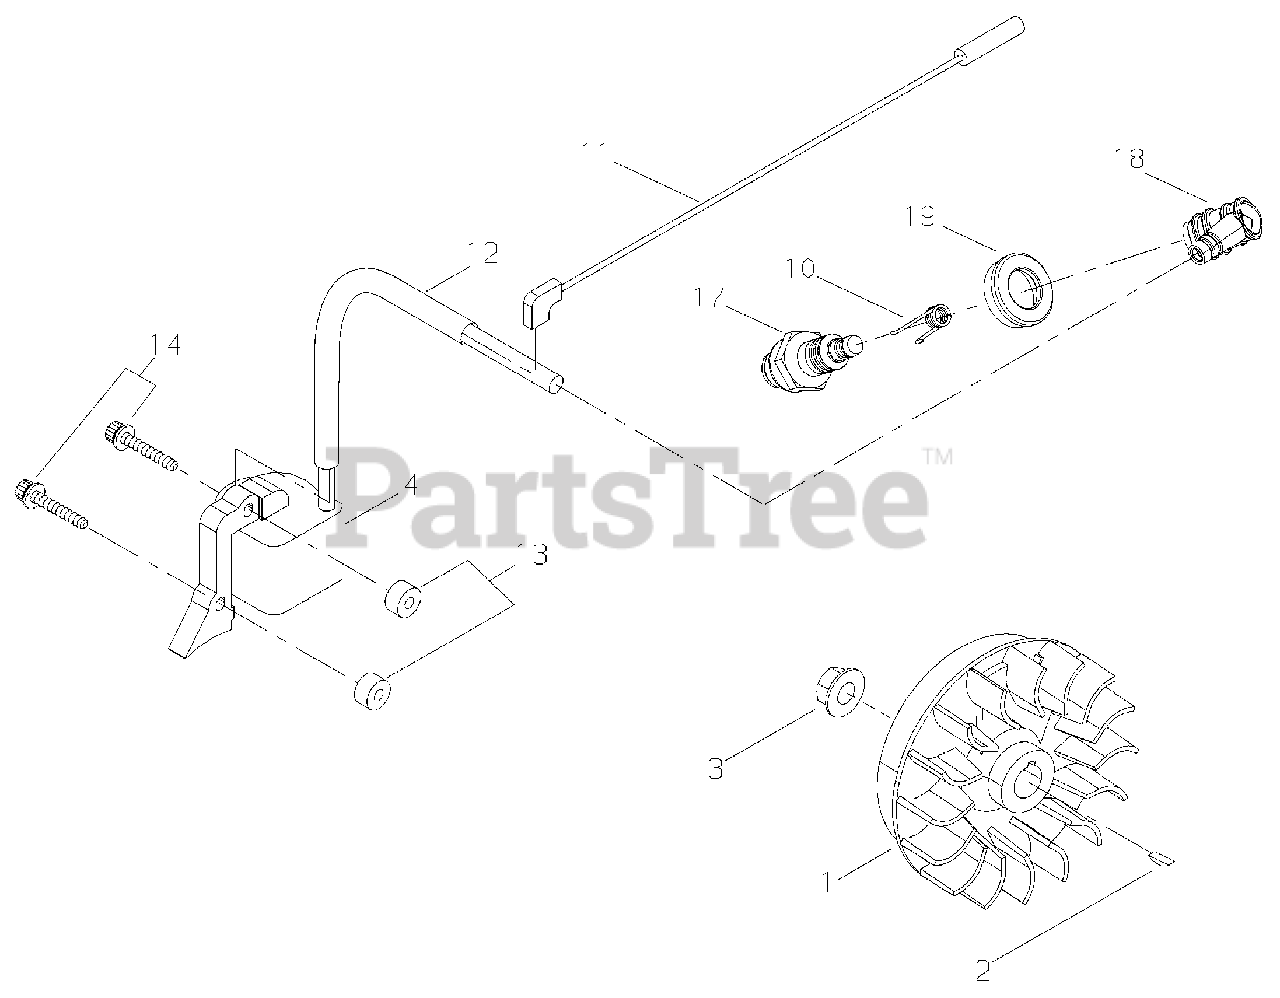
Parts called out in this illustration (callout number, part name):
1	FLYWHEEL
2	KEY - 3X10
3	NUT - 8
4	COIL, IGNITION
10	TERMINAL, SPARK PLUG CAP
11	LEAD - IGNITION
12	TUBE
13	INSULATOR
14	SCREW - 4X20
17	SPARK PLUG -- BPMR-6A
18	CAP, SPARK PLUG
19	SEAL, DUST
